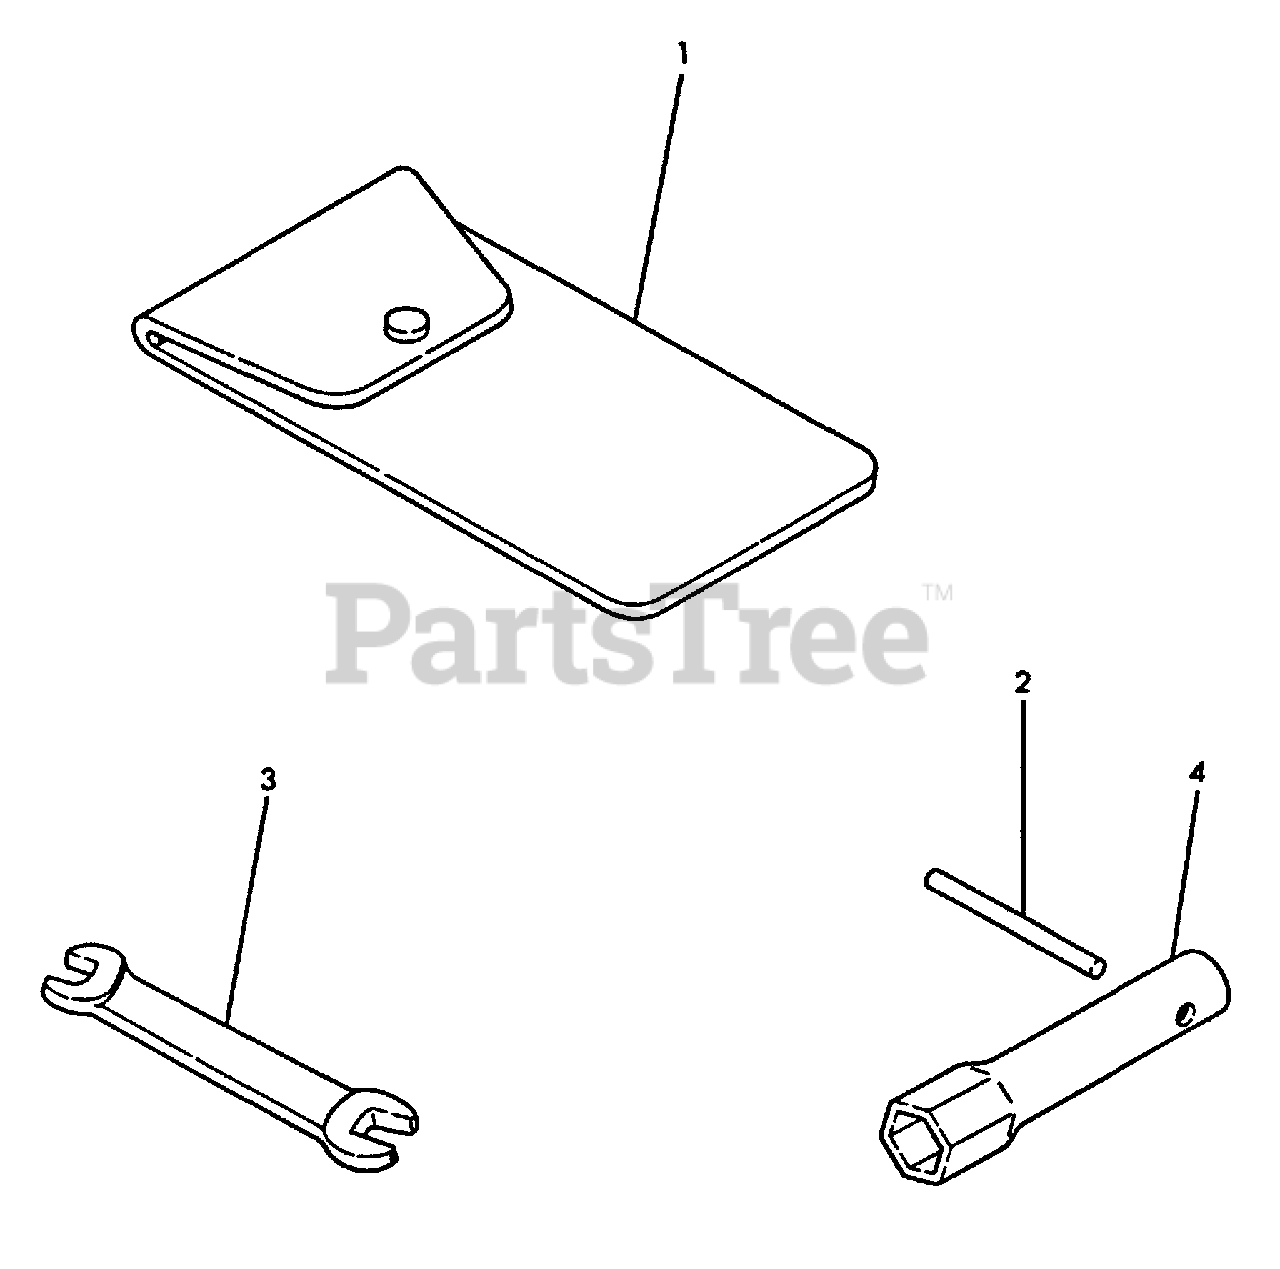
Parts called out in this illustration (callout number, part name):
1	BAG, TOOL
2	BAR
3	WRENCH 10×12
4	BOX WRENCH - 19×14
